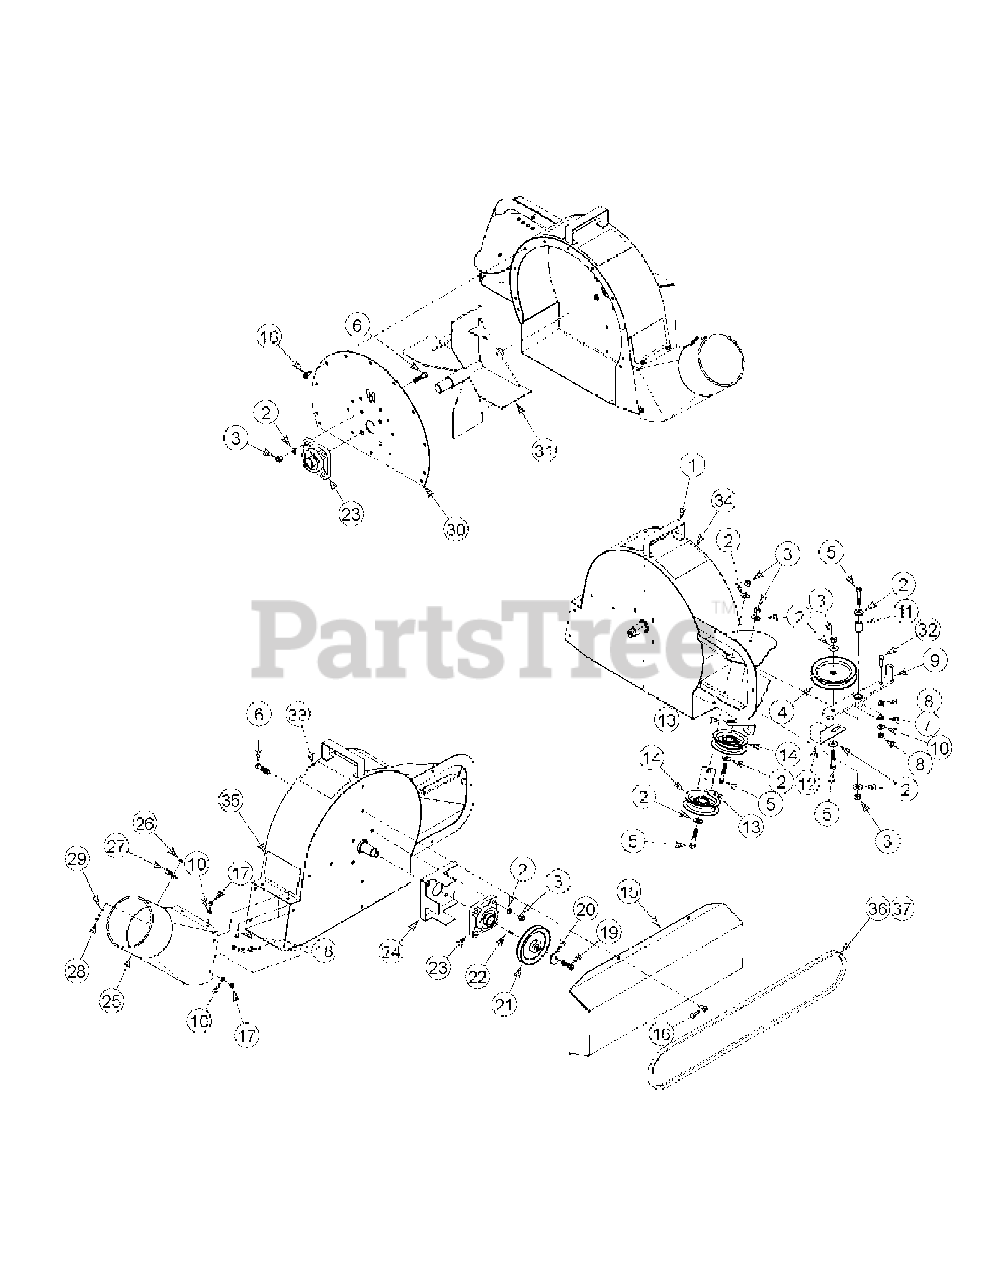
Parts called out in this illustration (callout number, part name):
1	BLOWER HOUSING
2	FLAT WASHER 5/16"
3	HEX NUT, NYLON INSERT 3/8"-16
4	IDLER PULLEY
5	CAP SCREW 3/8"-16 X 2" LONG
6	CAP SCREW 3/8"-16 X 1 1/2" LONG G5
8	HEX NUT, NYLON INSERT 5/16"-18
9	BELT TENSIONING ASSEMBLY
10	FLAT WASHER 1/4" USS
11	BELT TENSIONING BUSHING
12	BELT GUIDE, LARGE PULLEY
13	BELT GUIDE SMALL PULLEY
14	BACK SIDE BELT IDLER PULLEY
15	BELT COVER
16	SELF THREADING SCREW UNSLOTTED 5/16"-18 X 5/8" LONG
17	HEX NUT, NYLON INSERT 1/4"-20
18	CAP SCREW 1/4"-20 X 3/4LONG
19	BOLT, SERRATED FLANGE 3/8"-16 X 1.25" LONG
20	FLAT WASHER HEAVY
21	DRIVE PULLEY
24	BELT GUIDE
25	TRANSITION CHUTE
26	HEX NUT, NYLON INSERT, #10-24
27	SPRING CLIP
28	MACHINE SCREW #10-24X 1/2" LONG
29	FLAT WASHER #10 FENDER
30	BLOWER COVER
32	CAP SCREW 5/16"-18 X 1" LONG
33	LABEL, DANGER TURN OFF MOWER
34	LABEL, DANGER ROTATING BLADES
35	LABEL, DANGER THROWN OBJECT
36	BELT 48" DECK
37	BELT 54" DECK
37	BELT 60" DECK
